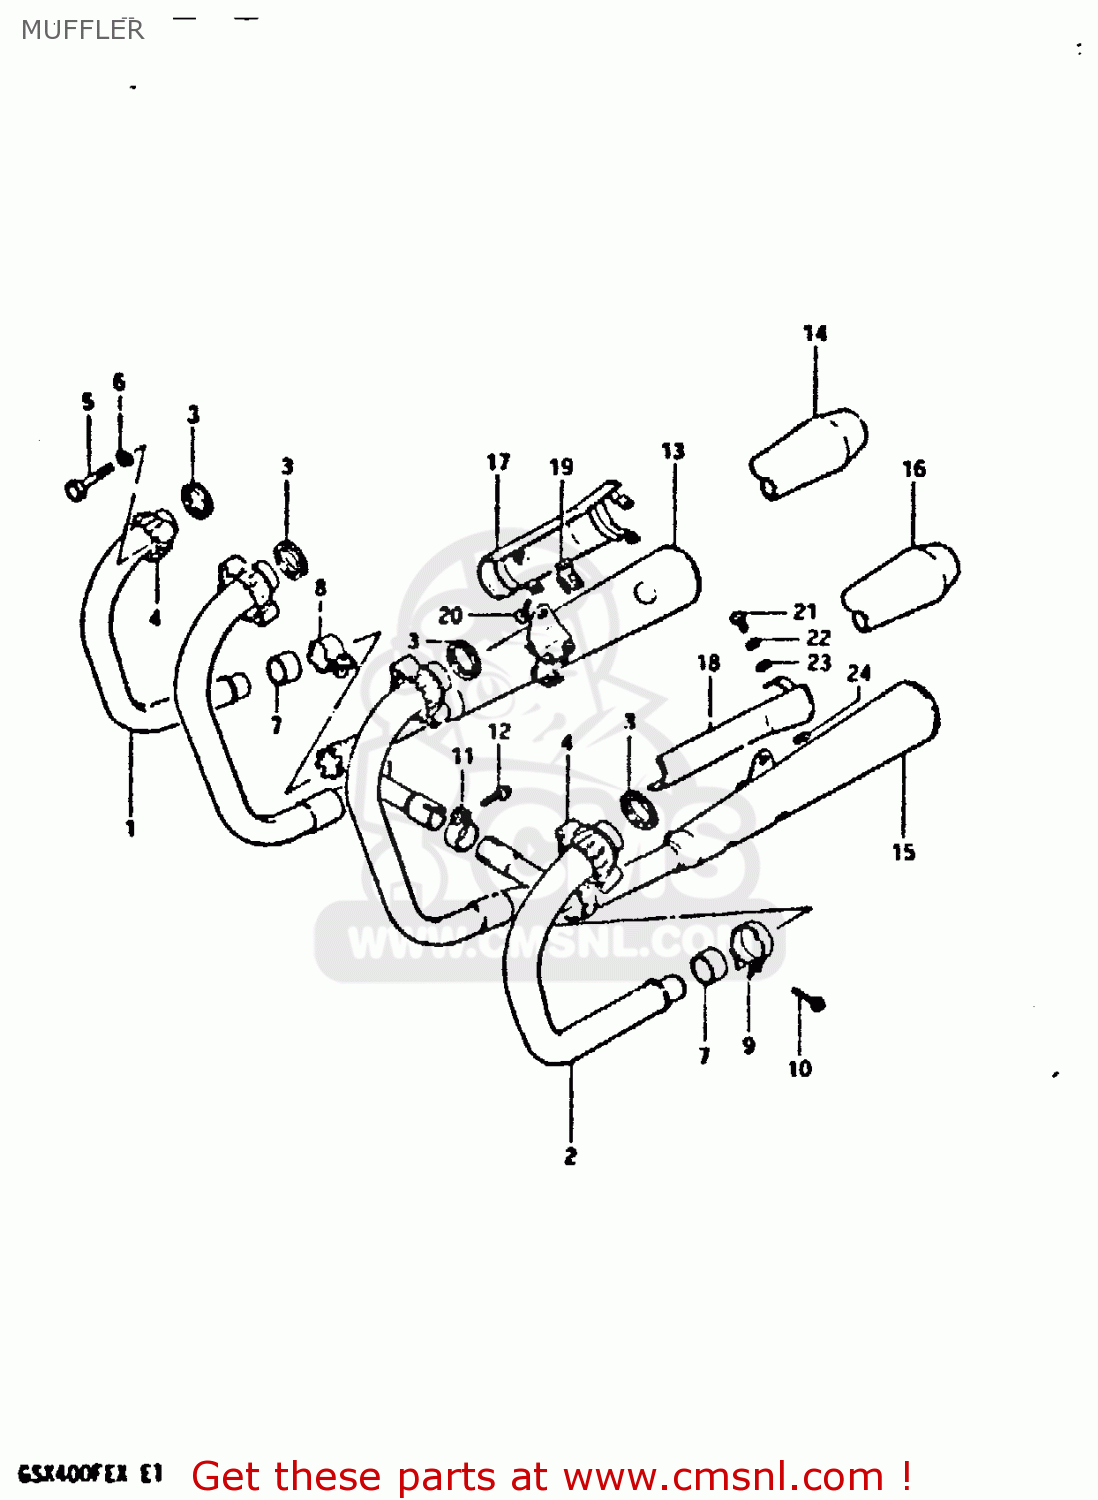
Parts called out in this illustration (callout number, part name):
1	PIPE, EXHAUST RH
2	PIPE, EXHAUST LH
3	GASKET,EXHAUST PIPE (NAS)
4	CLAMP,EXHAUST PIPE
5	BOLT 8X40
6	LOCK WASHER
7	CONNECTOR,MUFFLER
8	CLAMP,MUFFLER CONNECTOR
9	CLAMP,MUFFLER CONNECTOR
10	BOLT
11	CLAMP,EXHAUST COUPLER
12	BOLT,REAR
13	MUFFLER, RH
15	MUFFLER, LH
17	COVER, MUFFLER RH
18	COVER, MUFFLER LH
19	CLAMP
20	SCREW
21	SCREW
22	LOCK WASHER
23	WASHER
24	GASKET 6.2X12X1.5 (MCA)
